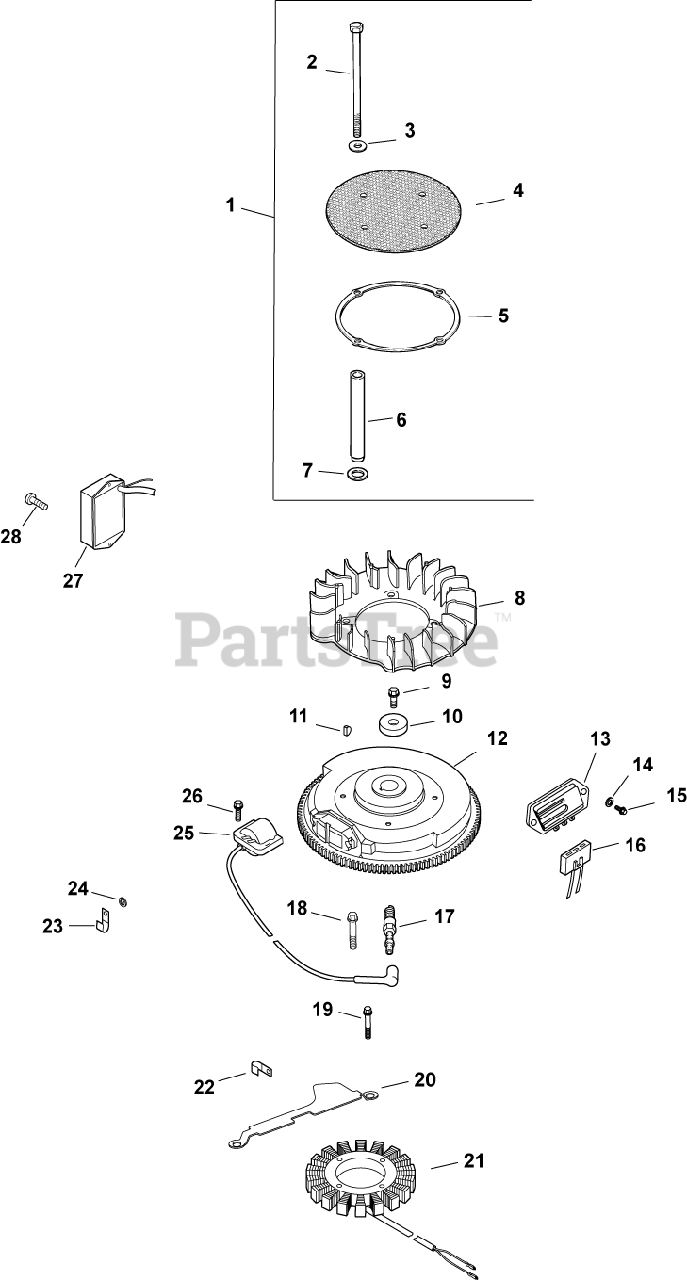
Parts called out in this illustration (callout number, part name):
1	KIT, CHOPPER SCREEN
2	SCREW, CAP M6X1.0X99.5
3	WASHER, FLAT 1/4" (O.D. 1/2")
4	SCREEN, GRASS-USE 24 162 41-S
5	RING, SUPPORT USE 25 141 08-S
7	WASHER, SPRING 10 MM
9	SCREW, FLG M10X1.5X45 - (#25086361S)
10	WASHER, FLAT 13/32"
11	KEY, 3/16" X 5/8"
12	FLYWHEEL ASSEMBLY-USE 24 025 58-S
13	REG/RECT-15 AMP (KM)-USE 41 403 10-S
14	WASHER, FLAT 3/16"
15	SCREW, PHL HD #11-16X7/8"
16	CONNECTOR, BODY (KM)-USE 25 155 41-S
17	PLUG, SPARK (STD)
18	SCREW, M5X0.8X25 - (#25086402S)
19	SCREW, SKT SET #10-24X1/4"
20	BRACKET, STATOR WIRE
21	KIT, 15 / 20 AMP STATOR
22	CLIP, TUBE & WIRING (KM)
23	CLIP, CABLE
24	WASHER, FLAT 1/4" (O.D. 1/2")
25	MODULE, IGNITION
26	SCREW, FLG THD FRM M5X.8X20-(#25086399S)
27	MODULE, SPEED ADVANCE -USE 24 755 162-S
28	SCREW, THD FRM M4X0.7X10
2458452-S	MODULE, SPARK ADV -USE 24 584 89-S
